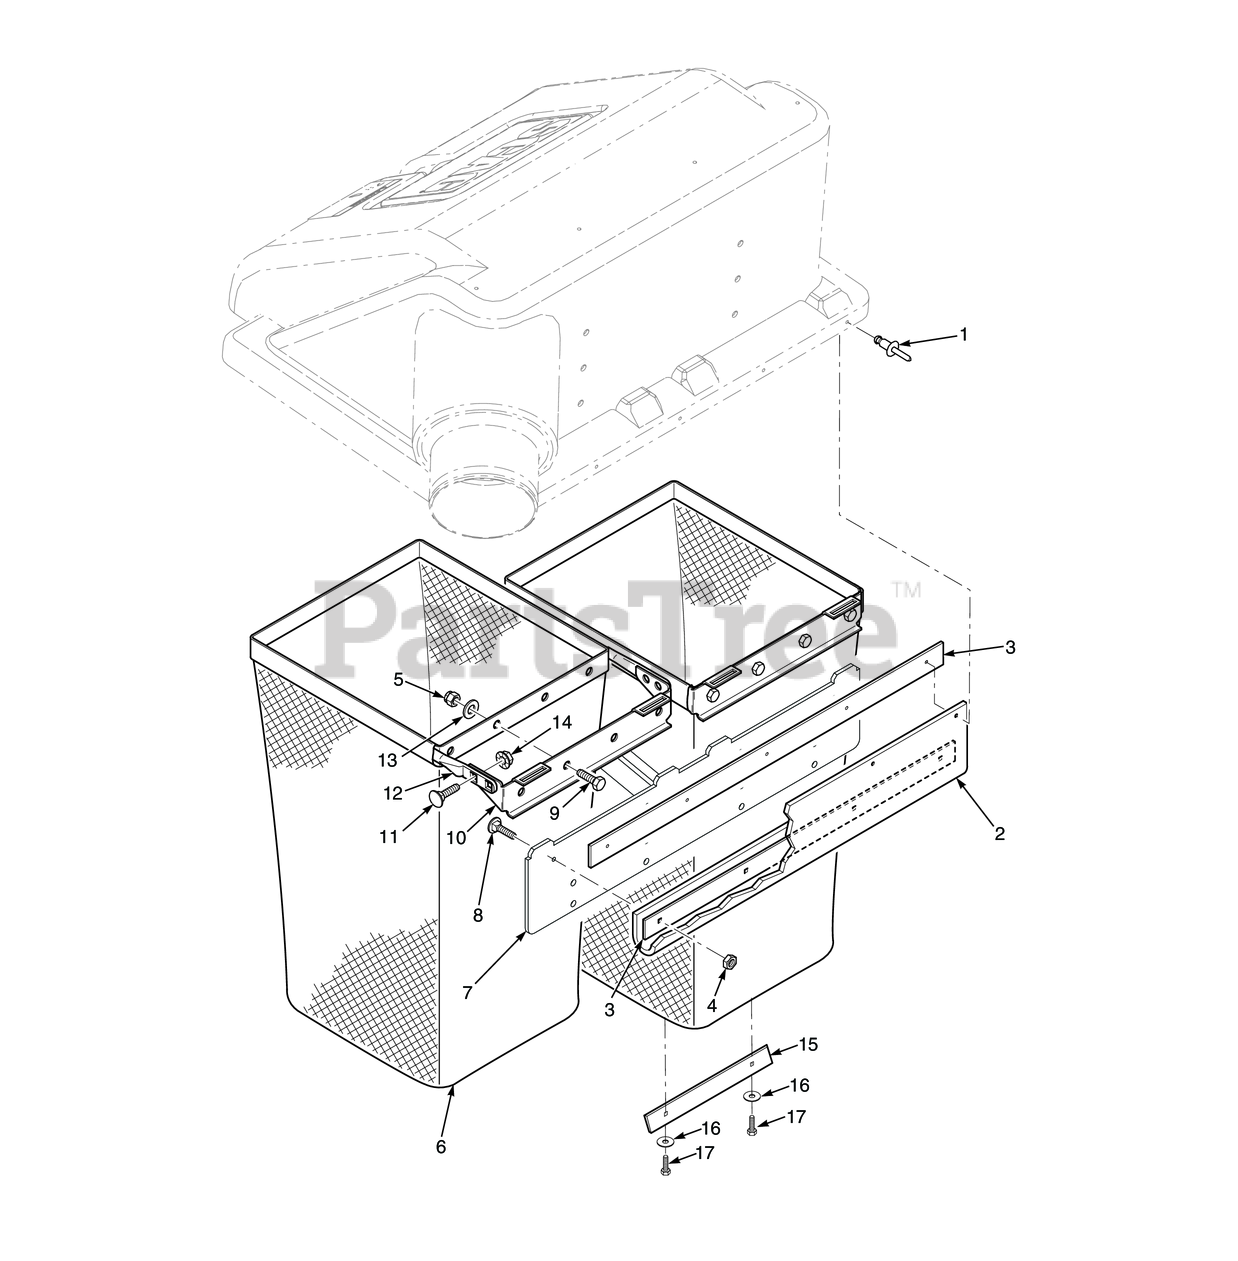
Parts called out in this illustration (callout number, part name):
1	Pop Rivet, 3/16 x .652"
2	Diode (part of wire harness)
3	Retainer, Seal
4	Bolt, Hex Hd. 1/2-13 x 9-1/2"
5	HEX NUT, ELASTIC STOP LOCK, 5/16-18
6	Bag Assembly
7	Frame Weldment, Bag Support
8	BOLT, HEX HEAD, 1/4-20 X 3/4 GR.5
9	BOLT, SERRATED FLANGE HEX HEAD 5/16-18 X 3/4"
10	Mount, Bag Frame Tube
11	Bolt, 5/16-18 x .75 RHSN Carriage
12	Tube, Bag Support
13	Flatwasher, 5/16-.375 x .875 x .083 (35BV & 37BV-EFI)
14	Nut, Serrated Flange 5/16-18 (Right Front Engine Mounting, Briggs and Kohler Only)
15	Handle
16	Flatwasher, 3/8-.406 x 1-1-1/2 x 7 Gauge
17	Bolt, 5/16 - 18 x 1 - 1/4" Hex Head
